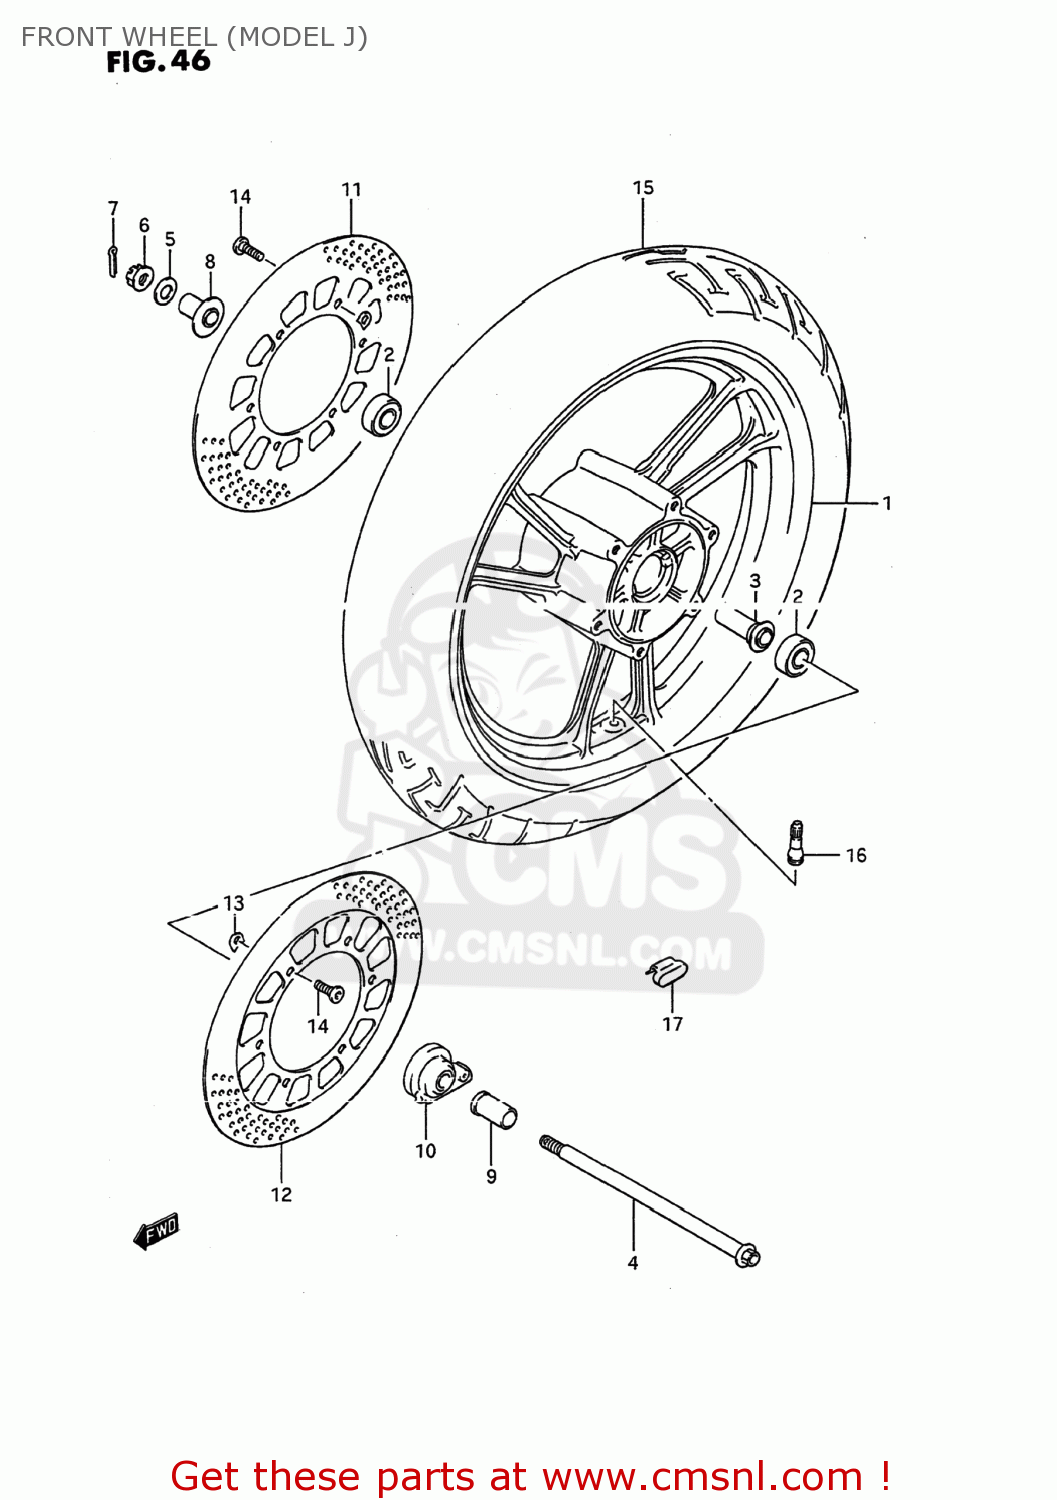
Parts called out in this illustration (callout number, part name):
1	WHEEL,FRONT (MT2.50X17)
2	BEARING
3	SPACER,FR HUB BEARING
4	AXLE,FR
5	WASHER
6	NUT
7	COTTER PIN
8	SPACER,FR AXLE
9	SPACER,FR AXLE,L
10	BOX ASSEMBLY,SPEEDOMETER GEAR
11	DISC,FRONT BRAKE,RIGHT
12	DISC,FR BRAKE,L
13	SHIM,BRAKE DISC (NA)
14	BOLT
15	TIRE,FRONT
16	VALVE,TIRE
17	BALANCER,WHEEL
